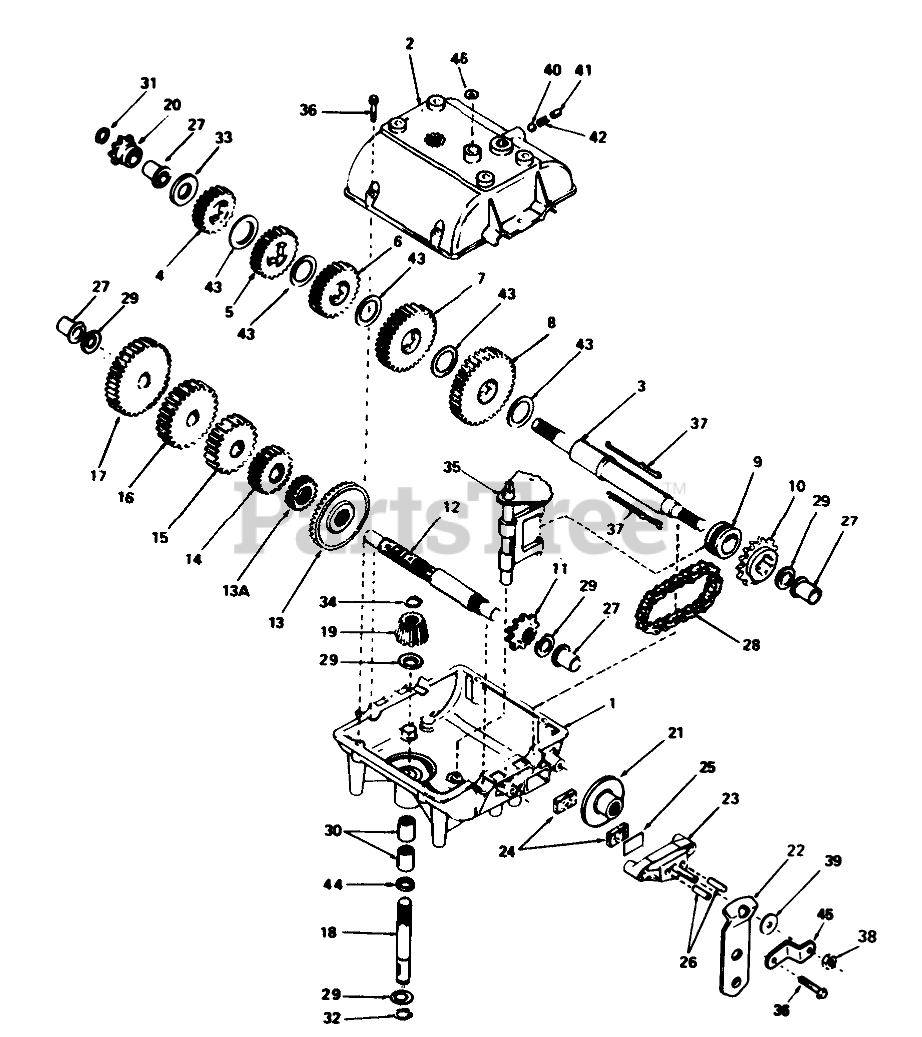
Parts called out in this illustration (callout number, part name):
1	Case-Transmission
2	Cover-Transmission
3	Shaft-Output
4	Gear-Spur 20 teeth
5	Gear-Spur (22 teeth)
6	Gear-Spur, 25 Teeth
7	Gear-Spur, 30 Teeth
8	Gear-Spur, 35 Teeth
9	Collar-Shift
10	Sprocket-18 Teeth
11	Sprocket-9 Teeth
12	Countershaft
13	Gear-Bevel (42 Teeth)
13A	Gear-Spur 15 Teeth
14	Gear-Spur, 20 Teeth
15	Gear-Spur, 25 Teeth
16	Gear-Spur (28 teeth)
17	Gear-Spur (30 teeth)
18	Shaft-Input
19	Bevel Pinion-Input
20	Sprocket (8Teeth)
22	Lever-Brake
23	Nozzle-Carburetor
24	Brake Pad
25	Brake Pad Plate
26	Dowel Pin
27	Bushing-Flange
28	Chain-Roller #41
29	Washer
30	Bearing-Needle
31	Piston Asm (.020 O S)
32	Ring-Snap
33	Washer
34	Ring-Retainer
35	Rod and Fork ASM
36	Ring Set (.020 O S)
38	Locknut
39	Washer
40	Ball-Steel
41	Screw-Set
42	Spring
43	Washer
44	O Ring
45	Bracket
46	Cut Seal-Square
